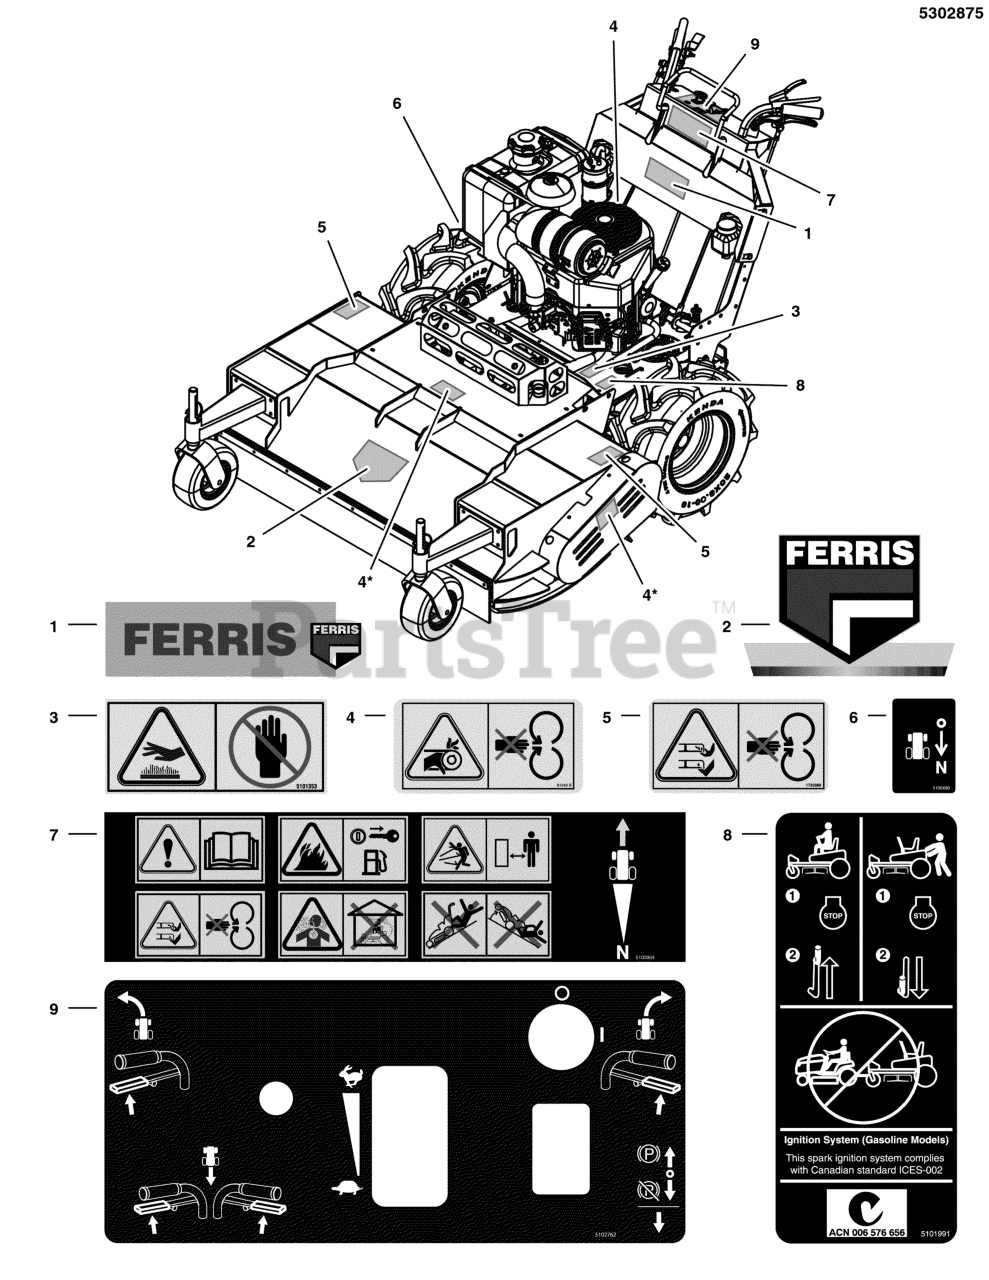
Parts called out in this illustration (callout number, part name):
1	DECAL, FERRIS TEXT & LOGO
2	DECAL, FERRIS SHIELD
3	DECAL, HAND IN FLAME
4	* DECAL, CE DANGER
5	DECAL-DANGER ROTATING BLADE SYMBOLS
6	DECAL, PEDAL
7	DECAL, CCW, CE
8	DECAL, TRANSAXLE RELEASE
9	DECAL, CONTROL PANEL, WB
